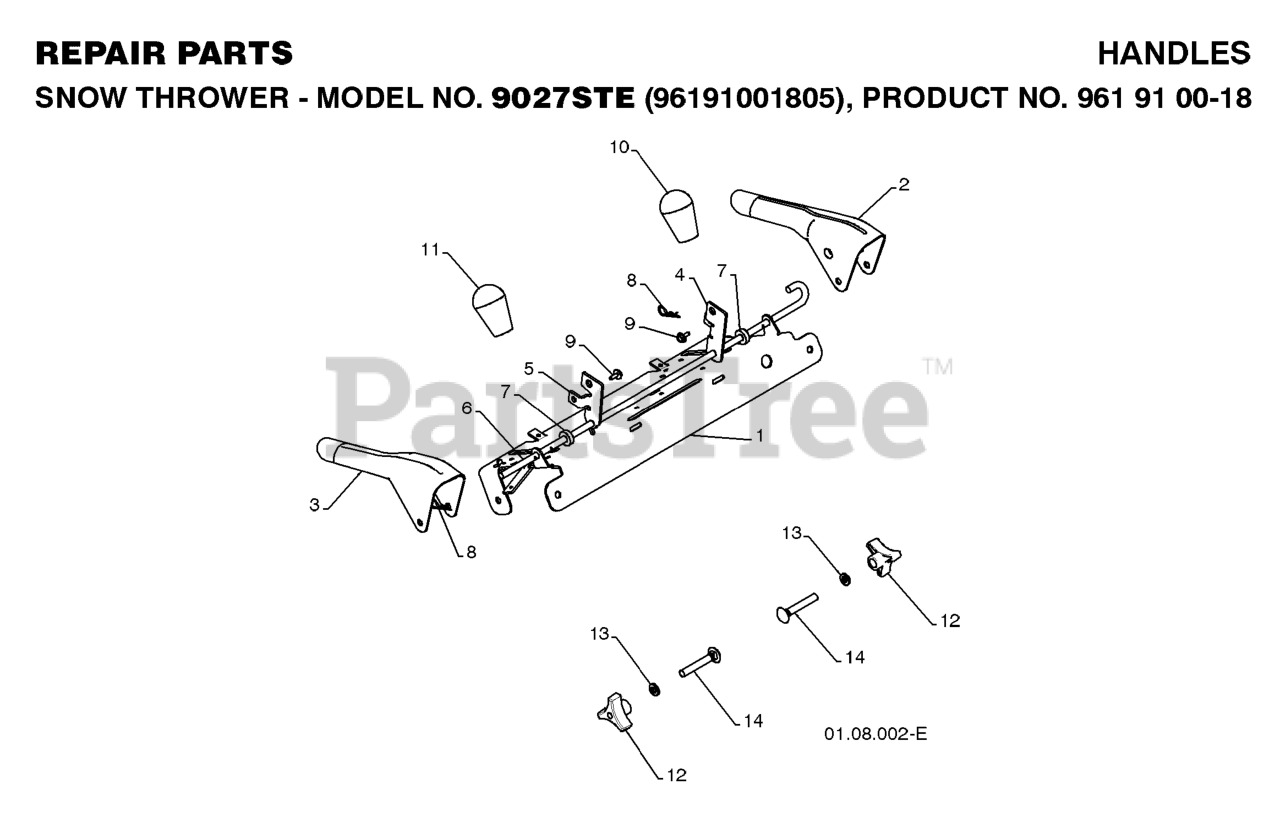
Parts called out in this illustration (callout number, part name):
1	PANEL.CONTROL.PNT.BLACK
2	LEVER.CONTROL.LH.PNT
3	LEVER.CONTROL.RH.PNT
4	ARM.TRACTION.ROD.YZ
5	ARM.IMPELLER.ROD.
6	BAIL.CONTROL.INTERLOCK
7	SPACER.CONTROL.LEVER
8	SPRING RETAINER
10	KNOB LEVER, BLACK
11	RED KNOB SHIFTER
12	KNOB.HANDLE.3/8.TRI-POINT.BLAC
13	WASHER
14	BOLT 3/8-16 X 2-1/4
